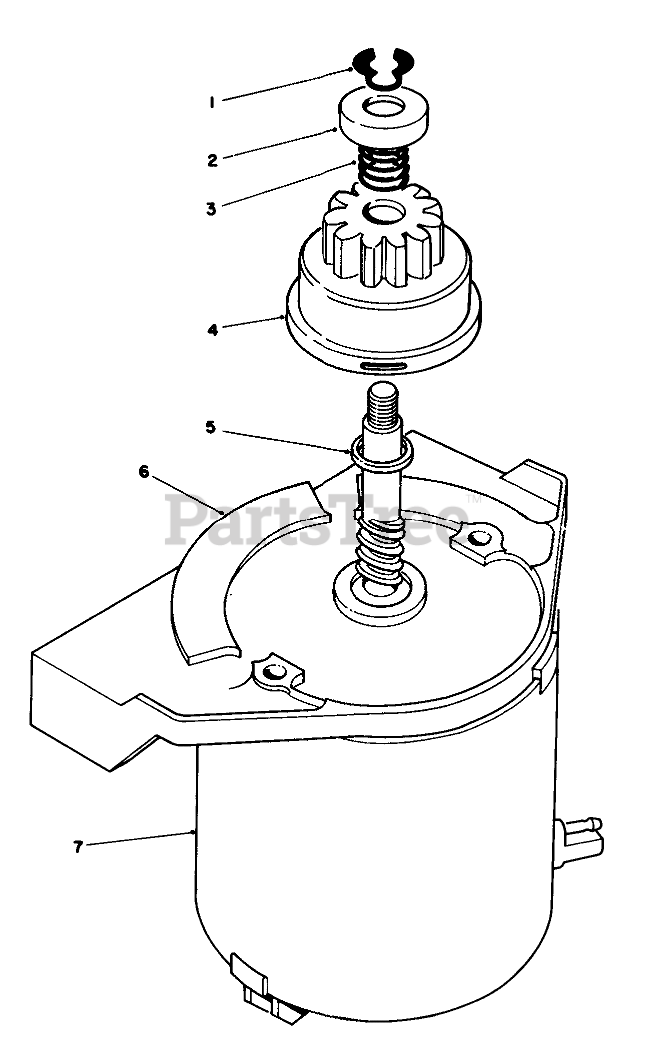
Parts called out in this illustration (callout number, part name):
1	RING-RETAINING
2	PINION STOP
3	COMPRESSION SPRING
4	PINION ASM
5	SPACER
6	Motor-Starter (Incl. Ref. #7)
7	END FRAME ASSY, MOTOR
